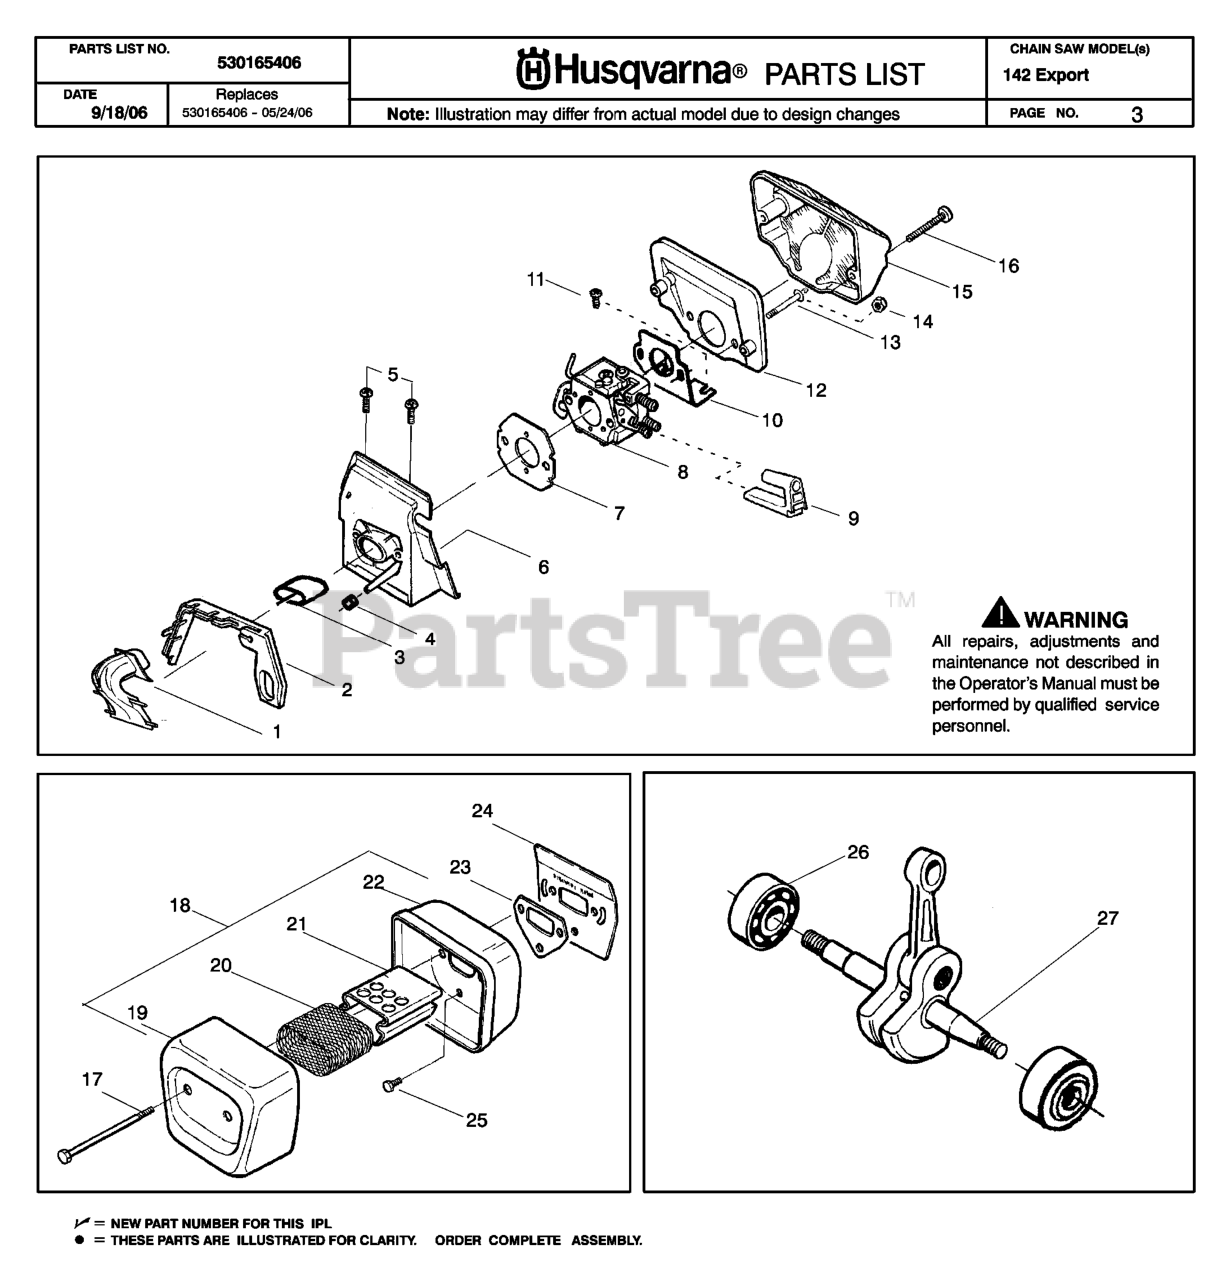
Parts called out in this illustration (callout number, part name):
1	INTAKE HORN
2	TURBO CLEAN SEAL
3	INTAKE PIPE
4	IMPULSE PIPE
6	CARB ADAPTOR
7	GSKT,CARB 36/41
8	CARBURETOR W-29
12	AIR FILTER (BOTTOM)
13	STUD-CARBURETOR
15	AIR FILTER - TOP
18	MUFFLER KIT
19	SILENCER COVER
20	SPARK ARRESTOR 36/41
21	FLAME PROTECTOR
22	SILENCER BODY
24	MUFFLER PLATE
25	BOLT-MUFFLER(SUPPORT)
26	BEARING & SEAL ASSEMBLY
27	CRANKSHAFT ASSY 36/41
